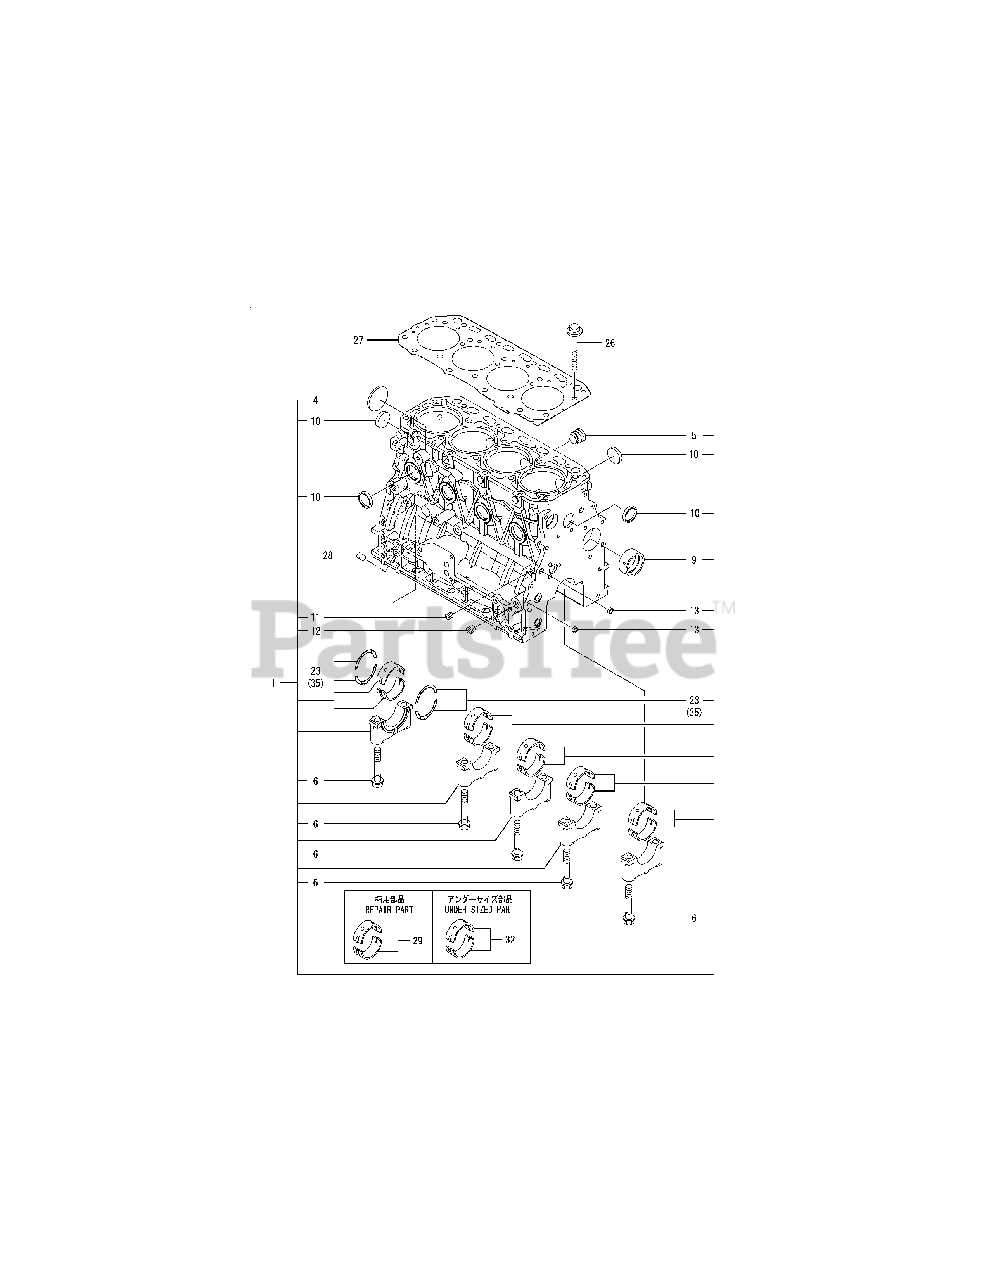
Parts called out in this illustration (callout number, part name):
1	BLOCK ASSY, CYLINDER
6	BOLT, METAL CAP
9	BUSH, CAMSHAFT A
23	METAL ASSY, THRUST
26	BOLT, CYLINDER HEAD
29	MAIN BEARING SET
32	MAIN METAL US=0.25
35	BEARING, THRUST.25OS
